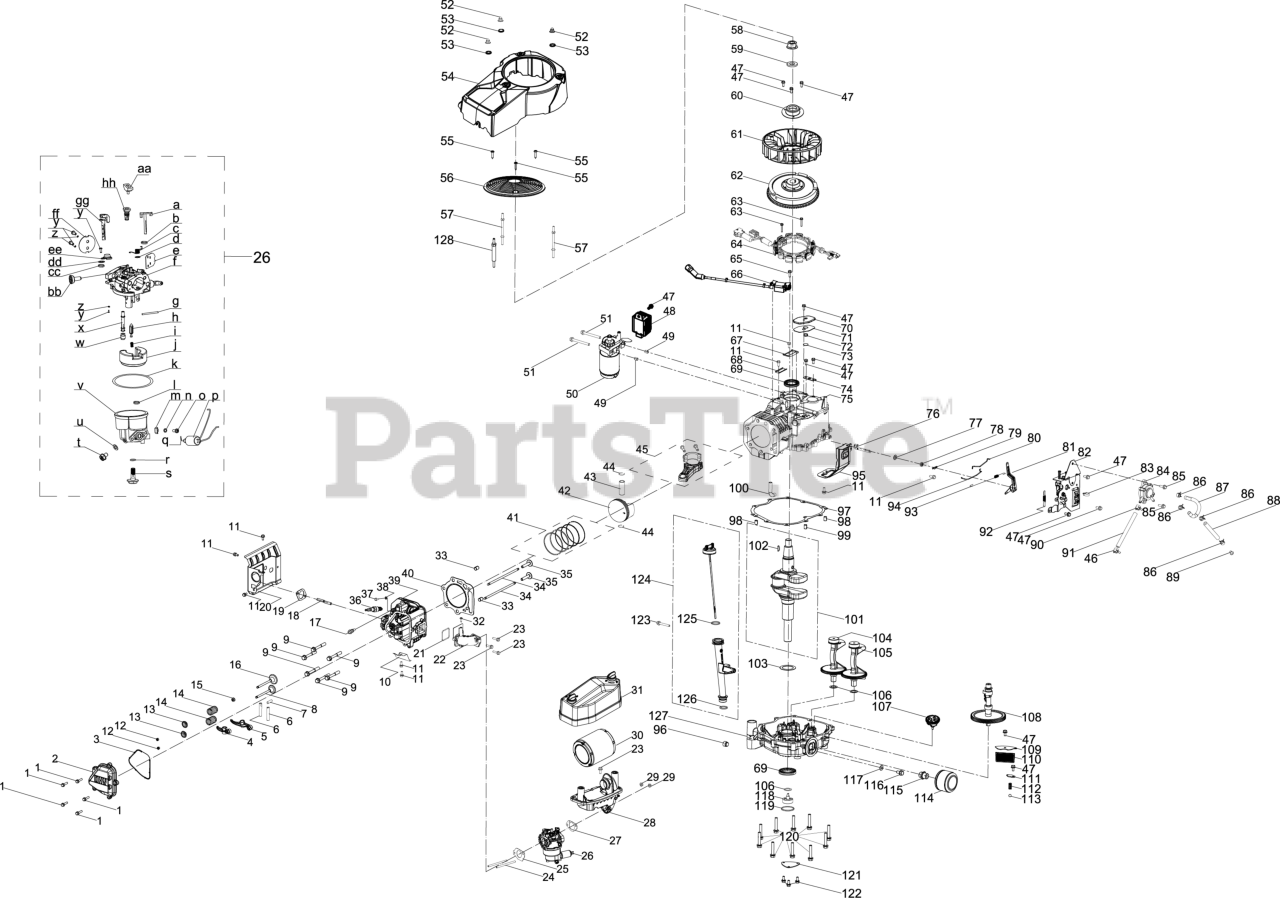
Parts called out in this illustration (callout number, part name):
1	BOLT M6-1 x 25 GR8.8
2	VALVE COVER
3	VALVE COVER GASKET
4	ROCKER ARM (EXHAUST)
5	ROCKER ARM (INTAKE)
6	ROCKER ARM SHAFT
7	CAMSHAFT PIN
8	EXHAUST VALVE
9	BOLT M10-1.25 x 70
10	SHROUD
11	BOLT M6-1 x 12 GR8.8
12	VALVE CAP
13	VALVE SPRING SEAT
14	VALVE SPRING
15	INTAKE VALVE SEAL
16	INTAKE VALVE
17	HOOK BOLT
19	EXHAUST GASKET
20	BAFFLE BRACKET
21	INTAKE PIPE RING
22	INTAKE PIPE
23	BOLT M6 x 22
24	STUD M6-1.00 x 92
25	INTAKE GASKET
26	CARBURETOR ASSEMBLY HY-8X90
27	AIR FLTER GASKET
28	INTAKE MANIFOLD
29	HEX NUT
30	AIR FILTER W/PREFILTER
31	AIR FILTER COVER
32	SELF TAPPING SCREW 4.8 x 16
33	PIN 12X16
34	SINGLE PUSH ROD
35	TAPPET
36	SPARK PLUG (F6RTC/RN11YC/BPR6ES)
37	BOLT M5-.8 x 10
38	FLAT WASHER: 5.3 x 10 x 1
39	CYLINDER HEAD
40	CYLINDER HEAD GASKET
41	PISTON RING SET
42	PISTON
43	PISTON PIN
44	PISTON PIN SNAP RING
45	CONNECTING ROD ASSEMBLY
47	BOLT M6-1 x 14 GR8.8
48	REGULATOR ASSEMBLY
49	DOWEL PIN
50	ELECTRIC STARTER
51	BOLT M8-1.25 x 80
52	ACORN NUT M6-1
53	WASHER
54	Shroud
55	BOLT 5.5 x 25
56	DEBRIS SHIELD
58	NUT M20 x 1.5
59	WASHER 20.5 x 5 x 40
60	COOLING FAN PLATE
61	COOLING FAN
62	Flywheel
63	BOLT M5 x 28
64	CHARGING COIL
65	BOLT-M6-1 x 28 GR8.8
66	IGNITION MODULE
67	WIRE PLATE
68	BREATHER SCREEN
69	OIL SEAL 38 x 58 x 8
70	BREATHER COVER
71	BREATHER COVER GASKET
72	BREATHER VALVE SPRING
73	BREATHER VALVE
74	BRACKET
75	CRANKCASE
76	GOVERNOR GEAR SHAFT
77	WASHER 8 x 0.8 x 16
78	GOVERNOR SEAL
79	GOVERNOR SHAFT CLIP
80	CHOKE LINKAGE
81	GOVERNOR LEVER
82	GOV GEAR BRACKET
83	FUEL LINE SUPPORT CLAMP
84	FUEL PUMP
85	BOLT M6-1 x 18 GR8.8
86	CARBURETOR HOSE CLAMP
87	BREATHER HOSE
88	Fuel Hose, 6.3X12.5X100
91	FUEL HOSE 6.3x12.5x180
92	GOVERNOR SPRING
93	THROTTLE LINKAGE SPRING
94	THROTTLE LINKAGE
95	SHROUD - RIGHT
96	ENGINE PLUG 3/8 NPT
97	CRANKCASE COVER GASKET
98	DOWEL PIN 9 X 14
99	DOWEL PIN 7 X 14
100	VENTING HOSE
101	CRANKSHAFT ASSEMBLY
102	WOODRUFF KEY
103	WASHER 38.3 x 54 x 1
104	BALANCE SHAFT (LH)
105	BALANCE SHAFT (RH)
106	WASHER 17.2 x 26 x 1
107	GOVERNOR GEAR ASSEMBLY
108	CAMSHAFT
109	FILTER COVER
110	FILTER SCREEN
111	PRESSURE RELEASE COVER
112	PRESSURE RELEASE SPRING
113	OIL PUMP STEEL BALL
114	ENGINE OIL FILTER
115	SCREW JOINT OIL FILTER ADAPTER
116	BOLT M8 x 15
117	OIL DRAIN PLUG WASHER
118	OIL PUMP ASSEMBLY
119	GASKET
120	BOLT M8 x 45
121	OIL SEPARATOR
122	SCREW M6-1 x 16
123	BOLT M6-1 x 45 CL5.8
124	DIPSTICK ASSEMBLY
125	O-RING
126	O-RING
127	CRANKCASE COVER
128	STUD M6 X 113
